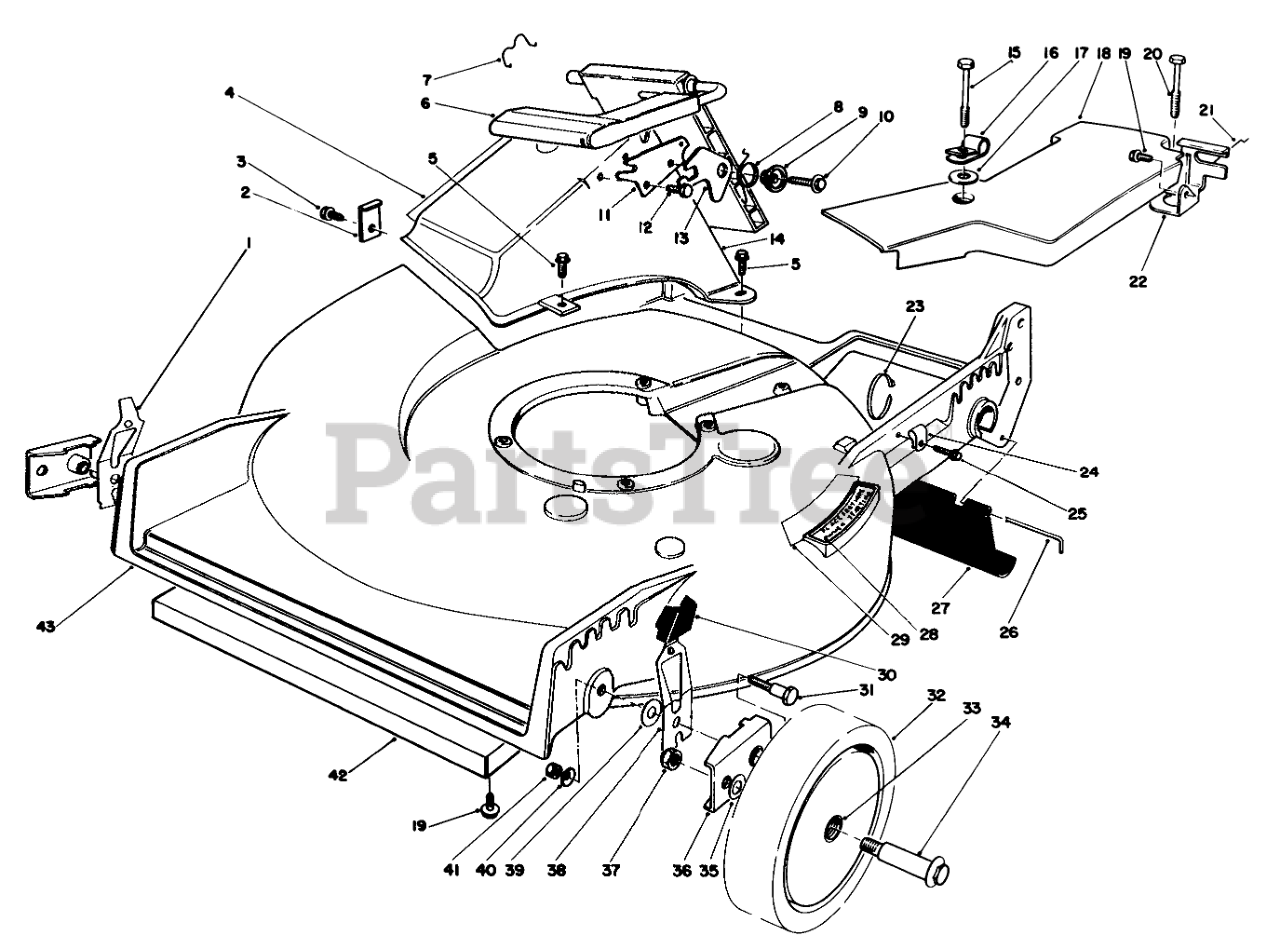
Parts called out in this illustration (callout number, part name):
1	R HP SPRING ARM ASM
2	TUNNEL CLIP
3	SCREW
4	ATTENTION DECAL
5	SCREW-HWH
6	Discharge Door Assembly
7	DOOR RET SPRING
8	TORSION SPRING
9	DOOR SPACER
10	SCREW-HWH
11	DOOR LATCH PLATE
12	SCREW-PLASTITE
13	SAFETY LATCH
14	Tunnel Discharge
15	SCREW-SPECIAL
16	CLAMP-CABLE
17	WASHER
18	Cover-Belt
19	SCREW-HWHTF
20	SCREW-HHFTF
21	RETAINER-CABLE
22	Bracket-Traction Adj.
23	TIE-CABLE
24	CLAMP-CABLE
25	SCREW
26	ROD-SHIELD
27	SHIELD-TRAILING
28	STEP PAD DECAL
29	Decal-Place Foot Here
30	KNOB-ARM
31	PIVOT SCREW
32	Wheel & Tire Assembly (Incl. Ref. #33)
33	BUSHING
34	WHEEL BOLT
35	WASHER
36	HP PIVOT ARM ASM
37	Nut
38	L. HP SPRING ARM ASM
39	WASHER-PIVOT
40	WASHER-BELLEVILLE
41	NUT-LOCK, NI
42	Shield-front
43	Housing
